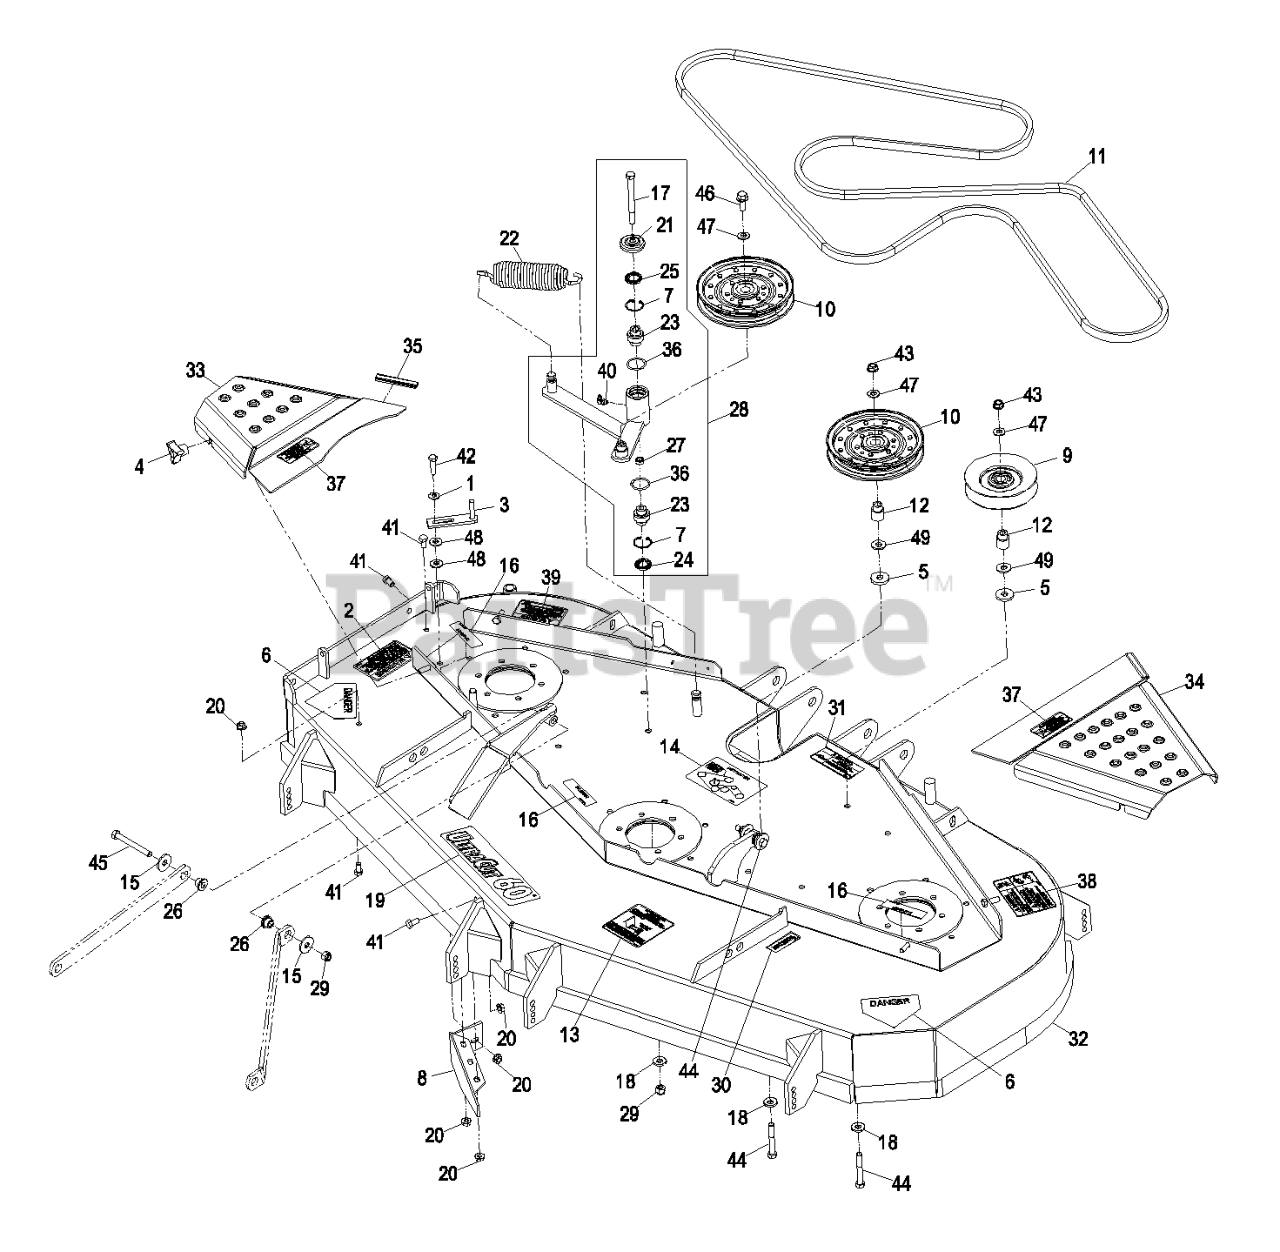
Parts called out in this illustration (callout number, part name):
1	WASHER-SPRING
2	DECAL-WARNING, DISCHARGE
3	GUIDE-BELT
4	KNOB-3 PRONG
6	DECAL-DANGER
7	RING-SNAP
8	WLD,BAFFLE DISCHARGE
9	PULLEY-IDLER
11	BELT,BLADE DRIVE
12	BUSHING-IDLER
13	DECAL,ANTISCALP
14	DECAL,BELT ROUTING
16	DECAL-COVER, MISSING
17	SCREW-HH
18	WASHER-BELLEVILLE
19	DECAL,ULTRACUT 60
21	GUARD-TOP
23	BEARING-SPHERICAL
24	SEAL-LIP, DOUBLE
25	SEAL-LIP, SINGLE
26	SPACER-STRUT
28	KIT,DECK IDLER LZ/XP
29	NUT-LOCK, NI
30	DECAL,BOLT TORQUE
31	DECAL-DRIVELINE
33	ASM,BELT SHIELD W/DECAL R
34	ASM,BELT SHIELD W/DECAL L
35	STRIP-SEAL
37	DECAL,CRUSHING HAZARD
38	DECAL,DECK WARNING
39	DECAL,CRUSHING HAZARD
40	FITTING-GREASE, 90 DEG
41	SCREW-HH
42	SCREW-HH
43	NUT-HHF, WHIZ
44	BOLT-CARR
45	SCREW-HH
46	SCREW-HHF
47	WASHER-FLAT
48	WASHER-FLAT
49	WASHER-FLAT
